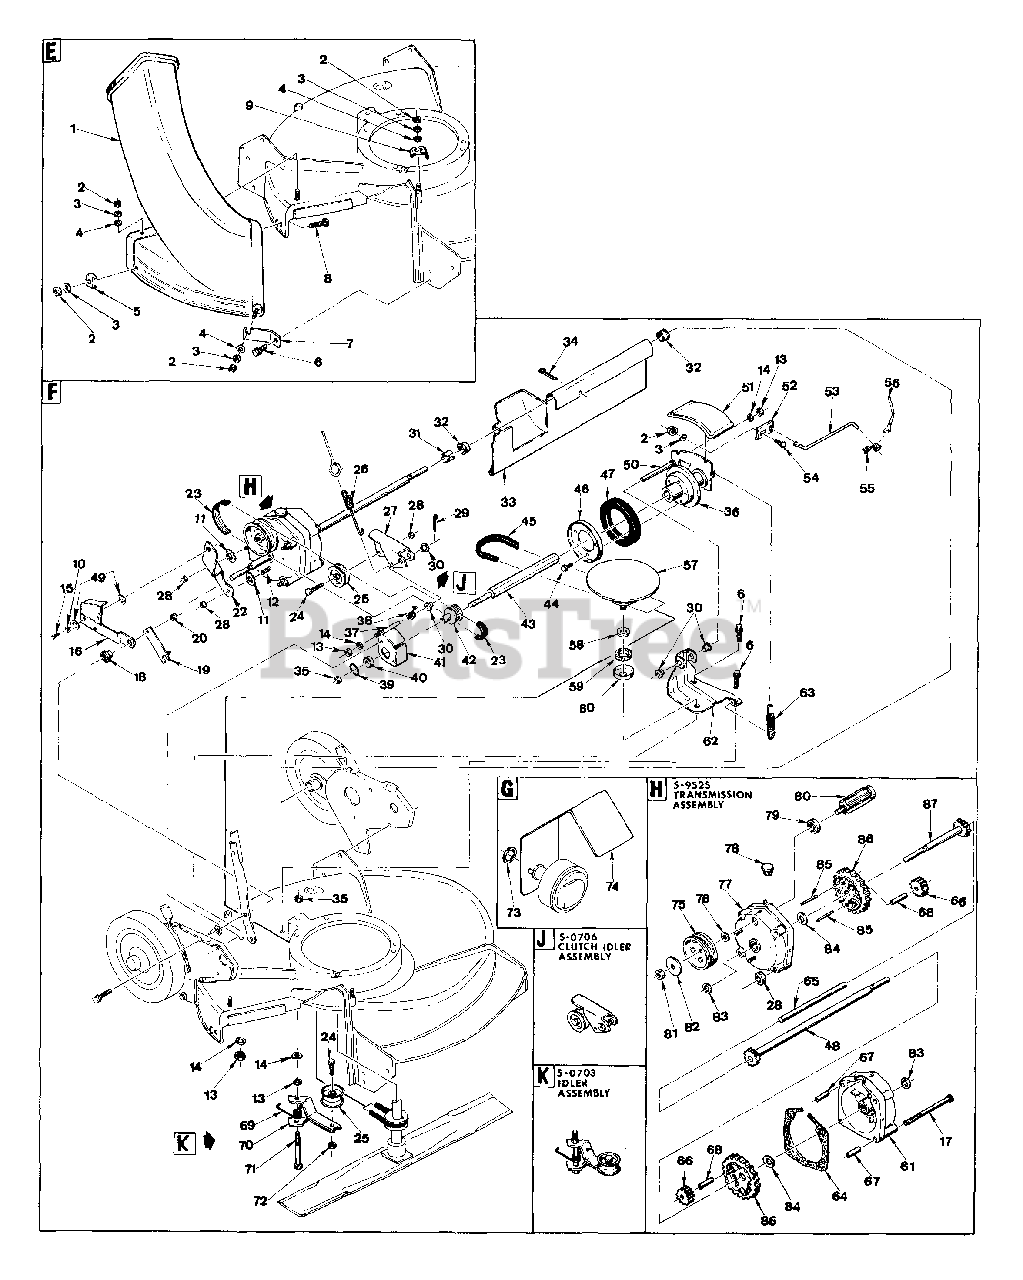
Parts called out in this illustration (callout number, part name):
1	Grass Chute Assembly
2	5/16-18 Hex Nut
3	5/16 Lock Washer
4	5/16 Flat Washer
5	Clip
6	5/16-18 x 5/8 SEMS ST.
7	Side Bracket
8	5/16-18 x 1 Carriage Bolt
9	Clamp
10	5/16 Internal Tooth Lock Washer
11	5/16 Int.-Ext. Tooth Lock Washer
12	1/4-28 x 1 H.H.C.S., Gr. 5
13	3/8-24 Hex Nut
14	3/8 Internal Tooth Lock Washer
15	5/16-18 x 3/8 HWST.
16	LINK, Differential
17	1/4-28 x 3 1/4 H.H.C.S.
18	Differential Link Bushing
19	Lower Belt Guide
20	5/16-24 Hex Lock Nut
22	Differential Bracket
23	Polly V Belt
24	1/4-28 x 1 1/4 H.H.C.S.
25	Idler Pulley
26	Spring-Clutch
27	Clutch Idler Arm
28	1/4 x 28 Hex Lock Nut
29	3/32 x 3/4 Cotter Pin
30	Nylon Bushing
31	Axle Spacer
32	Nylon Bushing
33	Rear Guard
34	1/8 x 1 1/4" Cotter Pin
35	3/8-24 Hex Lock Nut
36	Driven Disc Assembly
37	Idler Stud
38	Idler Torsion Spring
39	O-Ring
40	Bearing
41	Holder Half
42	Polly V-Pulley
43	SHAFT, Hex
44	SCREW, #10-24 x 1/2" Hex Washer Self-Tap (Torx)
45	Engine Belt
46	Tire Plate
47	RING, Driven (Rubber Disc)
48	Long Axle Assembly
49	Spring Washer
50	Thrust Plate Guide
51	Tire Cover
52	Transfer Rod Connector
53	Transfer Rod
54	5/16-18 x 3/4 Carriage Bolt
55	1/4" Rod Clip - Right Arc
56	Speed Control Lever
57	Drive Disc Assembly
58	3/8" SAE Washer
59	Felt Seal
60	Bearing Shield
61	Outboard Housing Assembly
62	Deck Bracket
63	Spring-Wheel Drive
64	Gasket
65	Shaft
66	12 Tooth Gear
67	Roll Pin
68	Shaft
69	Idler Spring
70	Idler Bracket
71	3/8-24 x 3 Hex Head Cap Screw
72	1/4-28 Hex Lock Nut
73	Internal Tooth Lock Washer
74	Heat Shield, Briggs Engine Only
75	Polly V-Pulley - 3 1/4 O.D.
76	Spring Washer
77	Inboard Housing Assembly
78	Plug
79	Ball Bearing
80	Input Gear Assembly
81	NUT, 5/16-24 Hex Lock, GR C
82	Clutch Washer
83	Seal
84	Thrust Washer
85	Roll Pin, 3/16 x 1 5/8
86	* USE 7060337 Kit, 46 Tooth, 12 Pitch Gear
87	Short Axle Assembly
50703	Idler Assembly
50706	Clutch Idler Assembly
59525	Transmission Assembly
